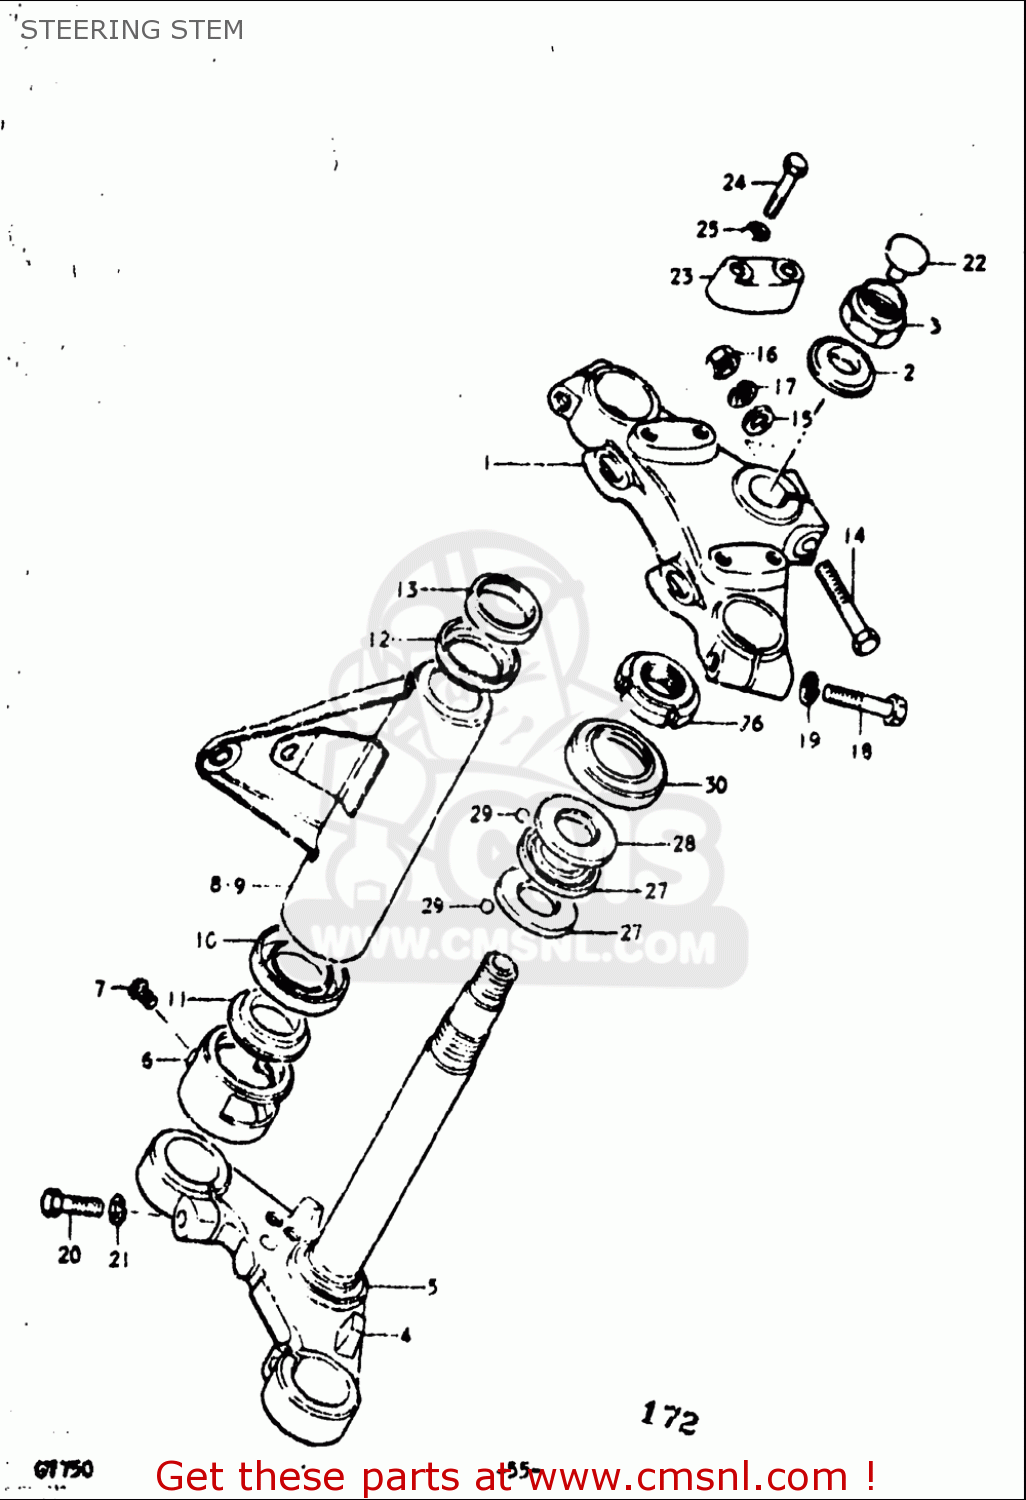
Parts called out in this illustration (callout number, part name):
2	WASHER
3	NUT
5	RACE,STEERING OUTER LWR
6	COVER,FORK LWR BRACKET
7	SCREW(5X6)
10	GUIDE
11	CUSHION,HEADLAMP BRACKET
12	GUIDE
13	CUSHION,HEADLAMP BRACKET UPR
14	BOLT
15	WASHER
16	NUT
17	WASHER,LOCK
18	BOLT
19	WASHER,LOCK
20	BOLT
21	WASHER,LOCK
22	CAP(OD:20)
23	HOLDER,HANDLE UPR
24	BOLT
25	WASHER,LOCK
26	NUT,STEERING STEM(25X44X10)
27	LACE,STEERING INNER LWR
28	LACE,STEERING OUTER UPR
29	BALL
30	DUST SEAL,STEERING UPR
